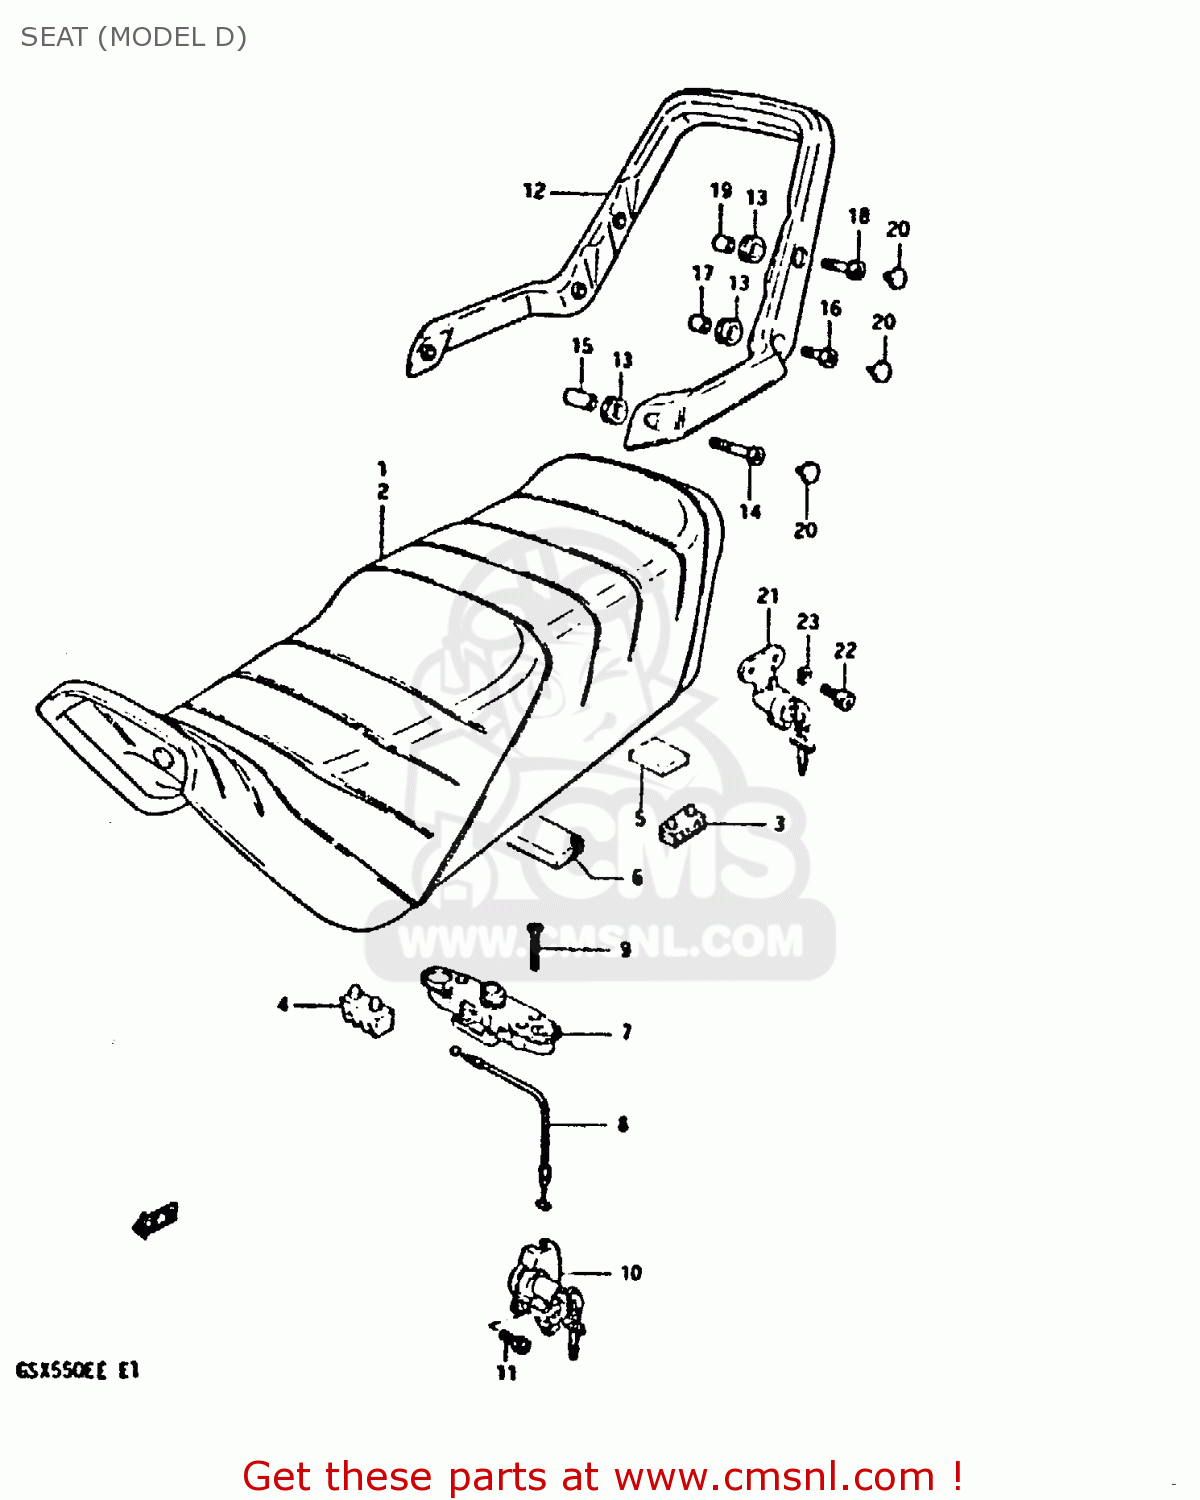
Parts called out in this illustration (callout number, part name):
1	SEAT ASSEMBLY
3	CUSHION,SEAT(40X20X15)
4	CUSHION,SUPPORT(50X25X32)
5	CUSHION,STRIKER
6	CUSHION(30X60X10)
7	LOCK ASSEMBLY,SEAT STRIKER
8	CABLE,SEAT LOCK
9	SCREW
10	LOCK ASSEMBLY,SEAT & HELMET
11	BOLT
12	HANDLE,PILLION RIDER
13	GROMMET,PILION RIDER HANDLE
14	BOLT
15	SPACER,PILLION RIDER HOLDER
16	BOLT
17	SPACER,PILLION RIDER HOLDER
18	BOLT
19	SPACER,PILLION RIDER HOLDER
20	CAP(OD:10)
21	LOCK ASSEMBLY,HELMET
22	BOLT
23	LOCK WASHER
